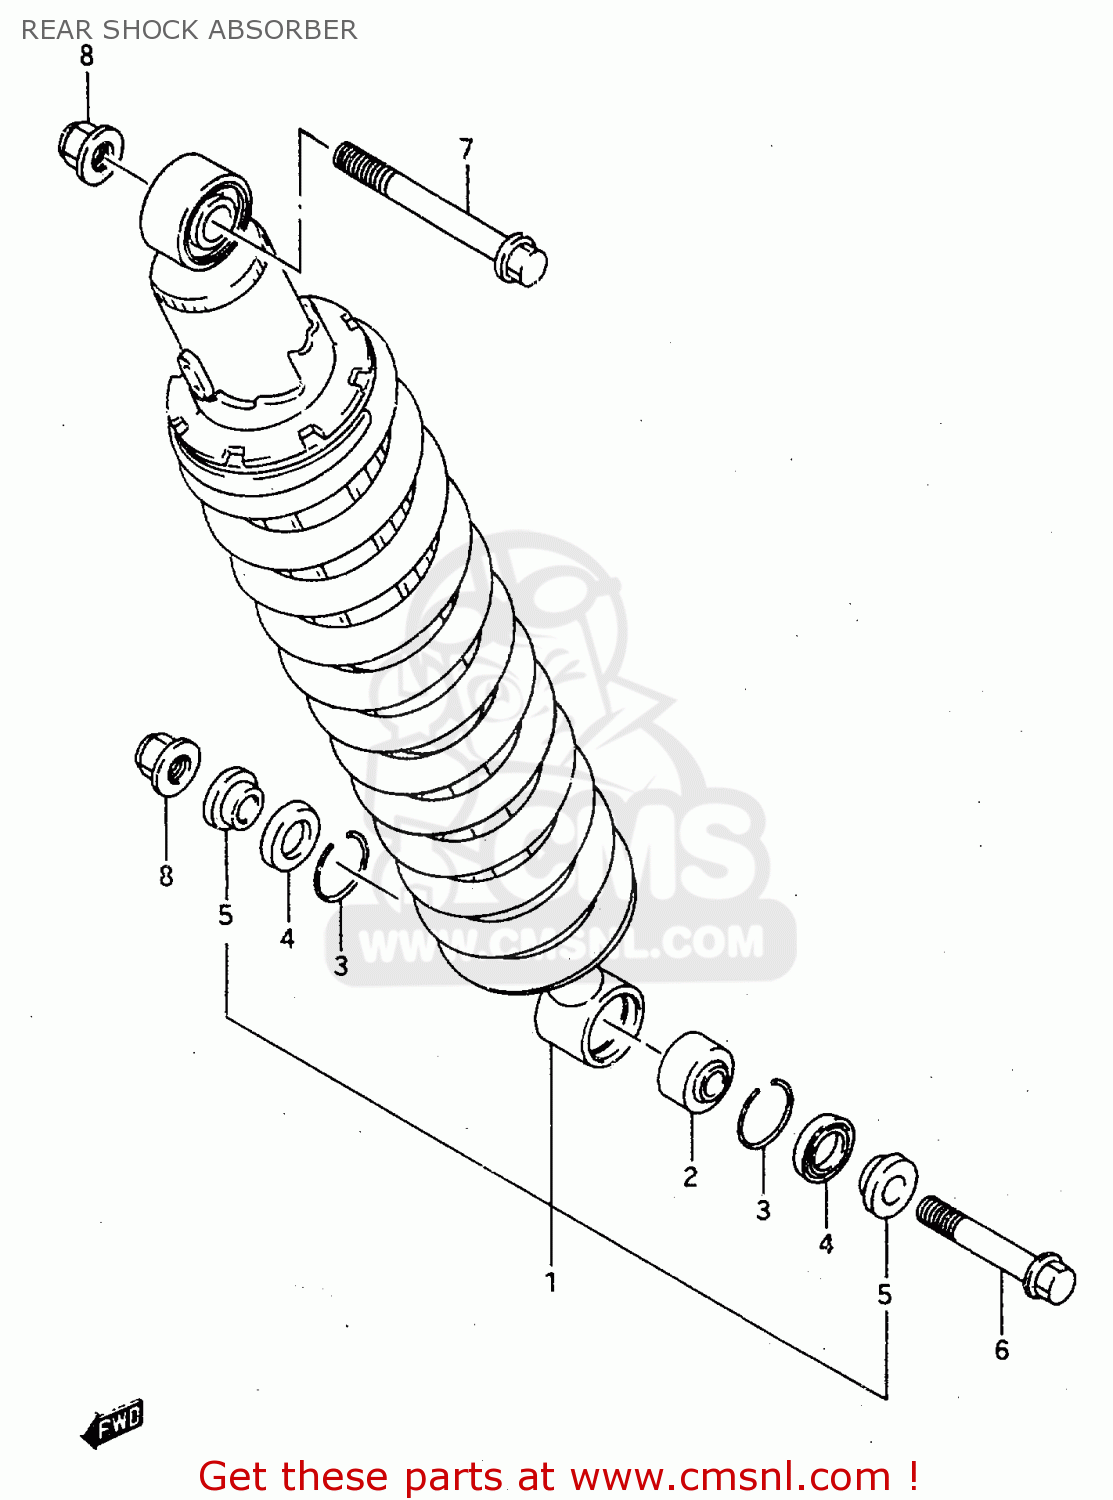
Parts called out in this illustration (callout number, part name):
1	ABSORBER ASSY,RR SHOCK(BLACK)
2	BEARING
3	RING,STOPPER
4	DUST SEAL
5	SPACER
6	BOLT(10X52)
7	BOLT,REAR SHOCK ABSORBER
8	NUT
